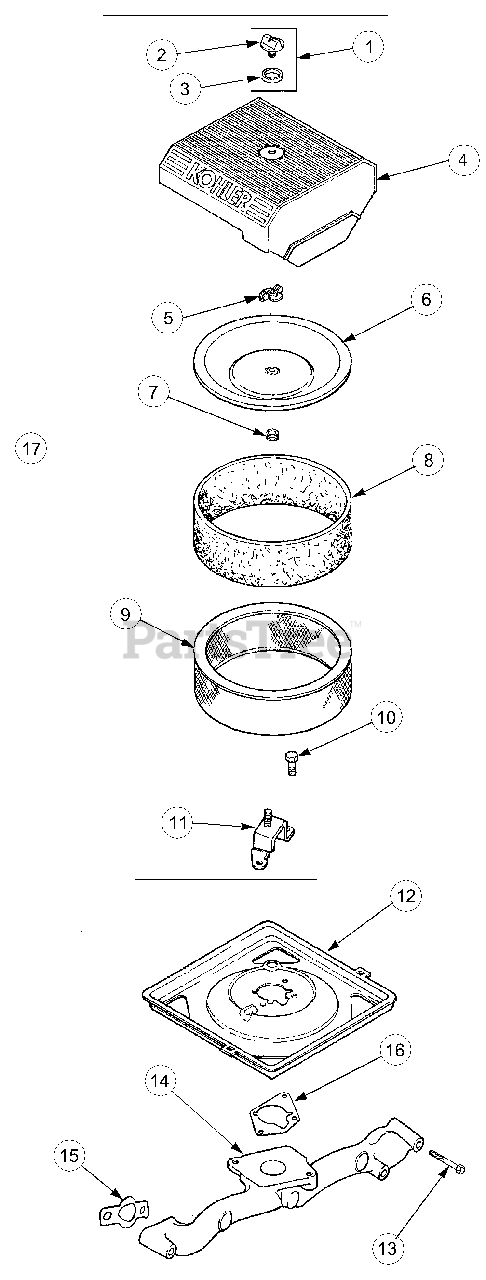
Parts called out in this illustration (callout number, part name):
1	Kit, Knob w/Seal
3	Seal, Air Cleaner Cover Knob
4	Cover, Air Cleaner
6	Cover, Inner Air Cleaner
7	Seal, Inner Air Cleaner
8	Precleaner, Element
9	Element, Air Cleaner
10	Screw, Hex Flange, M6 x 1.0 x 16
11	Bracket, Air Cleaner Base
12	Base, Air Cleaner
13	Screw, Hex Flange, M6 x 1.0 x 55
14	Manifold, Intake
15	Gasket, Intake Manifold
16	Gasket, Air Cleaner Base
17	Kit, Air Cleaner Cover
